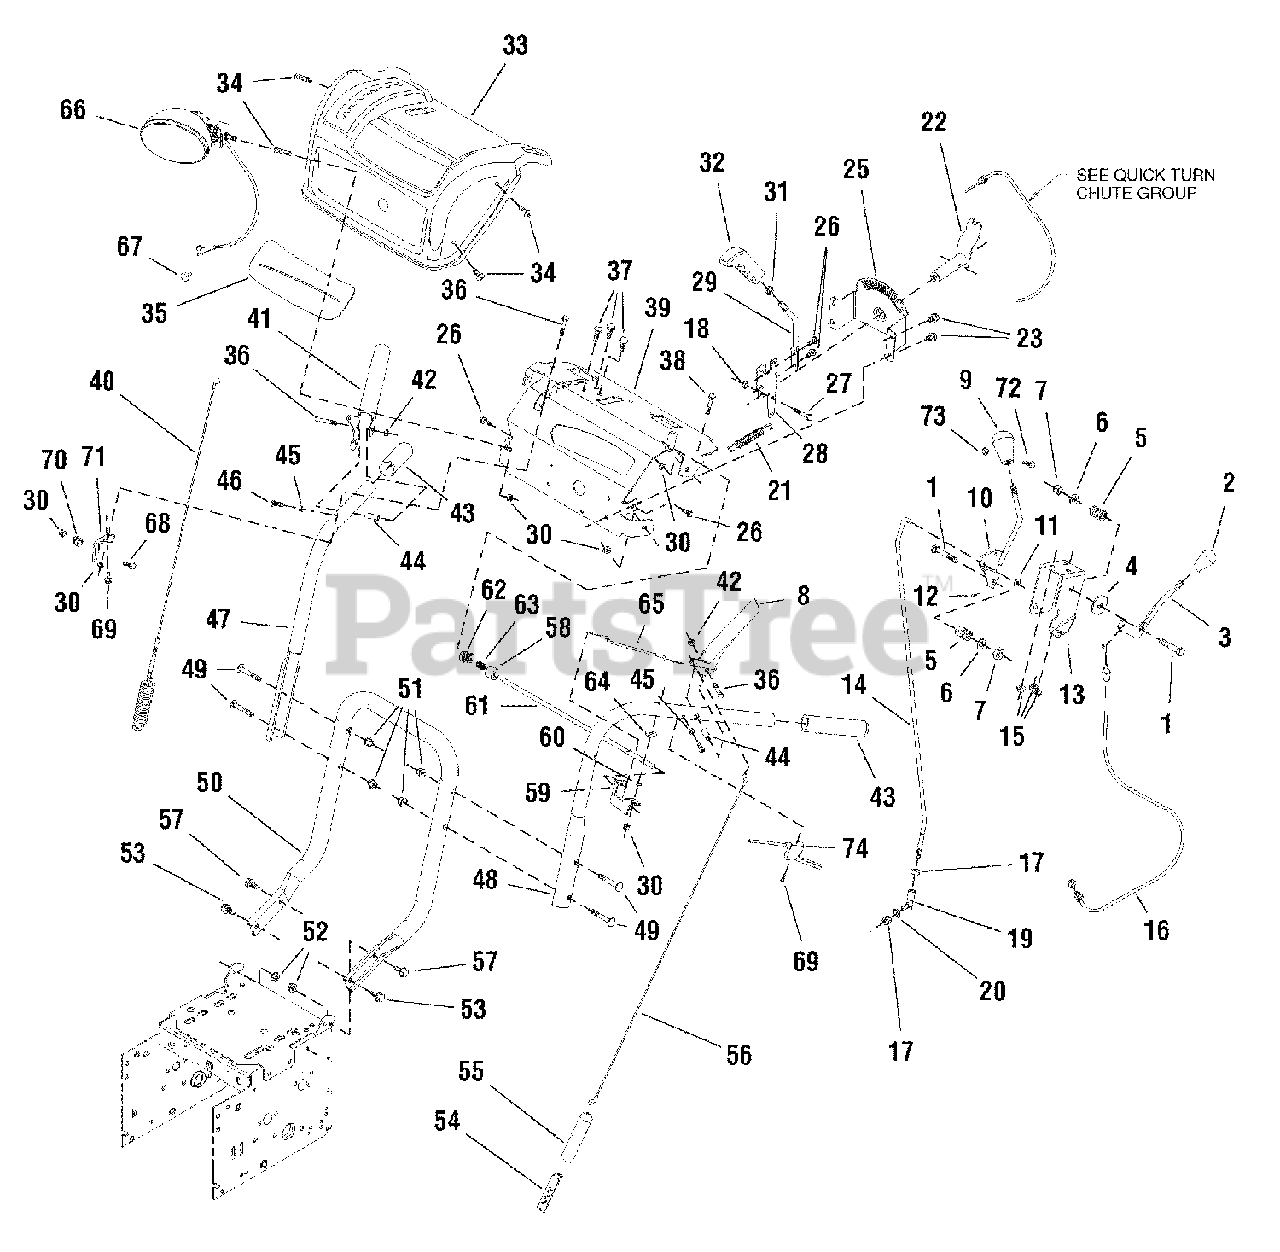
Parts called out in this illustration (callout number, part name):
1	CAPSCREW, Hex Head 3/8-16 x 2 G5
2	KNOB, Interior Thread 3/8-16
3	ROD, Chute
4	WASHER, 3/8
5	SPRING
6	WASHER, 3/8
7	NUT, Hex Lock ESNA Light 3/8-16
8	GRIP, Clutch, L.H.
9	KNOB, Slot Speed
10	ROD & PLATE ASSEMBLY, Speed Control
11	WASHER, 5/16
12	COTTER PIN
13	BRACKET, Trac & Deflector Control
14	ROD
15	NUT, Hex Flange 5/16-18 Whiz Lock
16	CABLE, Deflector Control
17	NUT, Hex 5/16-24
18	NUT, Hex Flange 1/4-20 Centerlock
19	BALLJOINT, Steel
20	LOCKWASHER, Spring 5/16
21	SPRING, Extension
22	TUBE & BRACKET ASSEMBLY, Cable
23	SCREW, Hex Washer Head Taptite 5/16-18 x 1/2
25	SUPPORT, Chute Control
26	SCREW, Hex Washer Head Taptite 1/4-20 x 5/8
27	BOLT, Shoulder 1/4-20
28	BRACKET, Support Quick Turn
29	ROD, Chute
30	NUT, Hex Lock ESNA Light 1/4-20
31	NUT, Hex Jam 3/8-16
32	GRIP, Lever 3/8-16
33	COVER, Panel
34	SCREW, Truss Head Torx Drive 1/4-20 x 3/4
35	BELLOWS, Black Rubber Quick Turn
36	CAPSCREW, Hex Head 1/4-20 x 1-1/2 G5
37	CARRIAGE BOLT, 5/16-18 x 3/4 G5
38	CAPSCREW, Hex Head 1/4-20 x 1-3/4 G5
39	SUPPORT, Dash Panel Cover
40	CABLE & SPRING ASSEMBLY, Auger Drive R.H.
41	GRIP, Clutch R.H.
42	NUT, Hex Centerlock 1/4-20
43	GRIP
44	SPACER
45	SPACER
46	SCREW, Pan Head Torx 1/4-20 x 3/4
47	HANDLE, Upper R.H. Tubular
48	HANDLE, Upper L.H. Tubular
49	CARRIAGE BOLT, 5/16-18 x 2-1/4 G5
50	HANDLE, Lower Tubular
51	NUT, Hex Flange 5/16-18 ESNA
52	NUT, Hex Flange 5/16-18 Two-Way Lock
53	SCREW, Hex Washer Head Taptite 5/16-18 x 3/4
54	BRACKET, Cable Adjusting
55	BOOT, Control Spring
56	CABLE, Front Drive
58	SPACER
59	BRACKET, Free Hand Control
60	SPACER, Powdered Metal
61	ROD & SPRING ASSEMBLY, w/Pin
62	WASHER-, 1/2
63	SPRING, Compression
64	WASHER, 1/4
65	ROD, Hold Down
66	HEADLIGHT ASSEMBLY, Oval Clear
67	FASTENER, Panel
68	CARRIAGE BOLT, 1/4-20 x 1-1/4 G5
69	SCREW, Pan Head Torx #10 x 1/2
70	SPOOL CABLE, Auger Control
71	BRACKET, Spout Cable
72	SCREW, Round Head Phillips #10-24 x 3/4
73	NUT, Hex Lock 10-24 w/Nylon Insert
74	CABLE & HANDLE ASSEMBLY
0640	WASHER, 1/2
